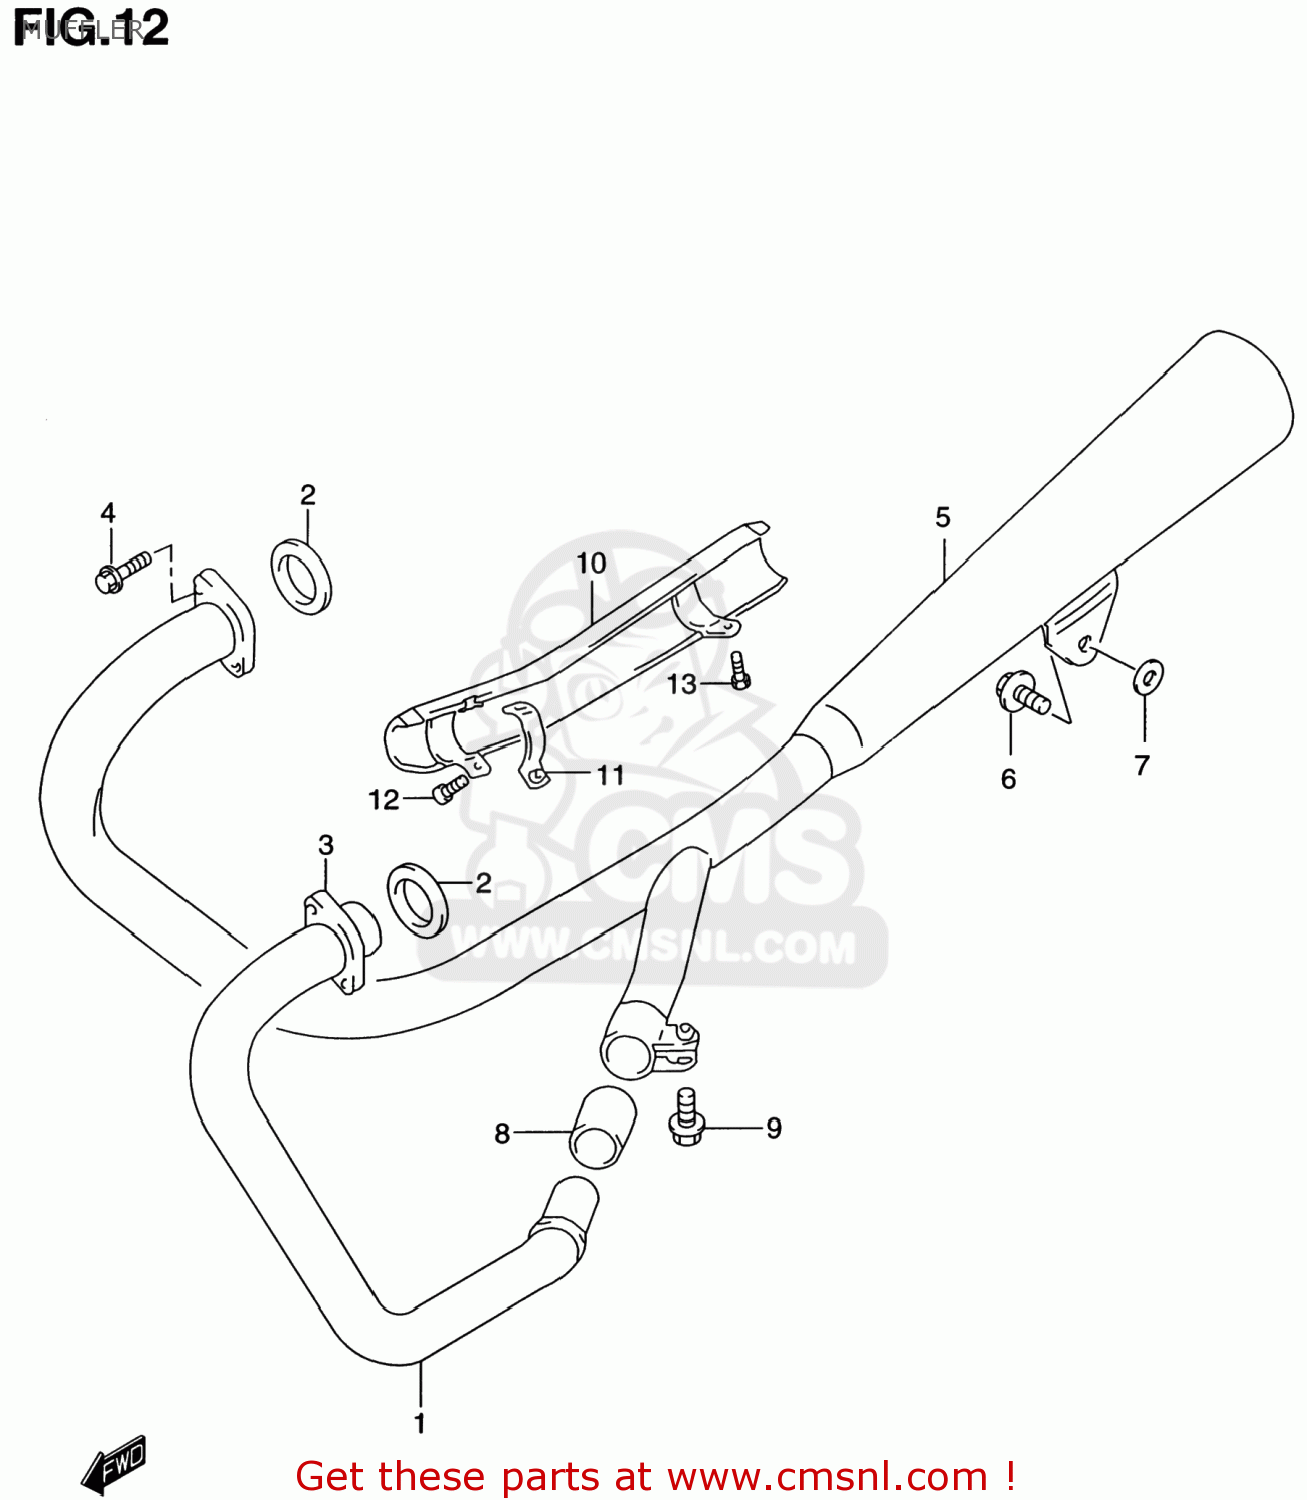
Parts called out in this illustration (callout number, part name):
1	PIPE,EXHAUST,L
2	GASKET,EXHAUST PIPE (NAS)
3	CLAMP,EXHAUST PIPE,L
4	BOLT(6X25)
5	MUFFLER
6	BOLT
7	WASHER
8	CONNECTOR,MUFFLER
9	BOLT
10	COVER COMP,MUFFLER
11	CLAMP,MUFFLER COVER
12	SCREW
13	SCREW
